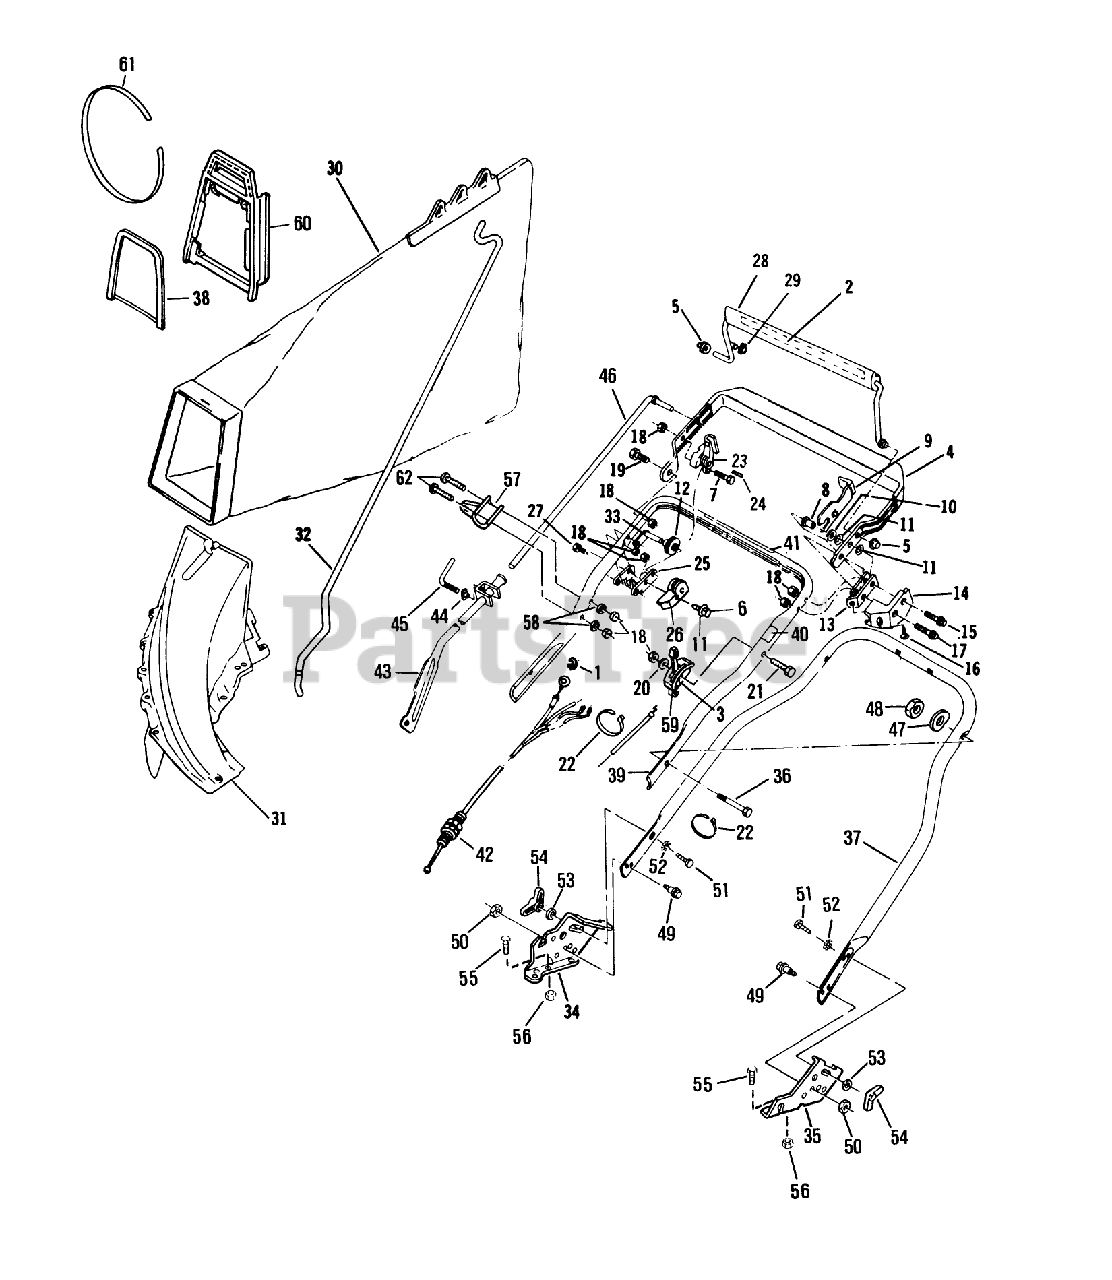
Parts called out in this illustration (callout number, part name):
1	RET. RING
8	SPACER
10	WASHER M
12	PULLEY PL
13	DOWN STOP
15	BOLT SHOU
16	SCREW F
17	SCREW
18	LOCKNUT E
19	BOLT
20	WASHER-FLAT
23	CAM HOFFER
29	NUT ACORN
30	ORDER 89816 THRU WHOLE GD
32	ROD GRASSBAG
38	CHUTE BRACE
42	CONTROL CABLE
43	CONTROL LEVER AY
46	CONTROL ROD
47	WASHER-CURVED
48	NUT-LOCK F
49	BOLT
50	NUT-JAM, LOCKING
52	LOCK WASHER LARSON
53	WASHER
54	NUT-WING
56	NUT-LOCK F
58	WASHER
60	CHUTE - ADAPTER
